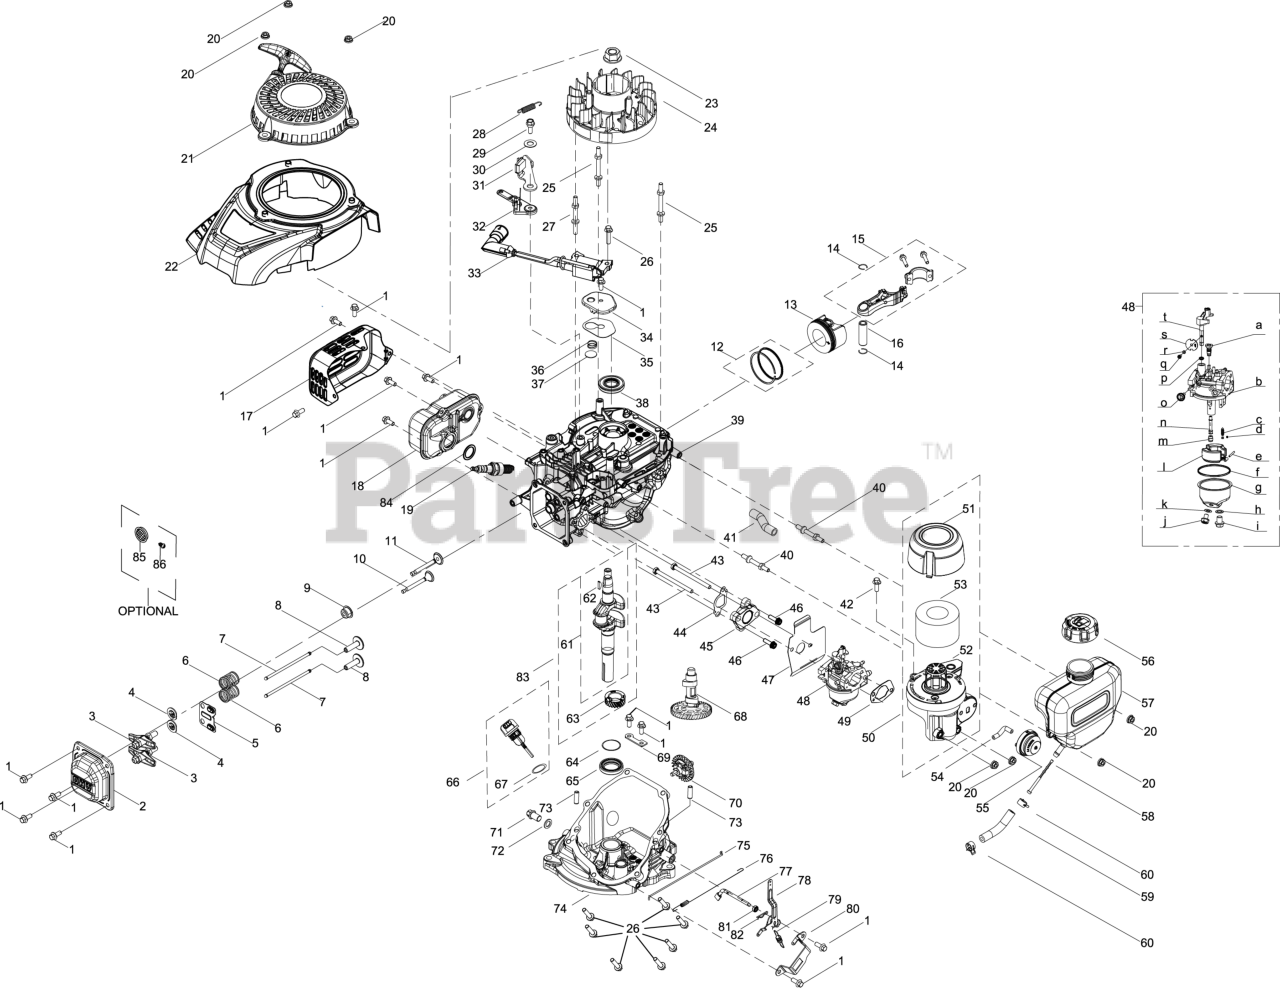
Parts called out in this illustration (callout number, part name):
1	BOLT M6-1 x 14 GR8.8
2	VALVE COVER
4	VALVE RETURN SPRING
5	PUSH ROD GUIDE
6	VALVE SPRING
9	INTAKE VALVE SEAL
10	EXHAUST VALVE
11	INTAKE VALVE
12	PISTON RING SET
14	WRIST PIN CLIP
15	CONNECTING ROD
17	MUFFLER GUARD
19	SPARK PLUG (F6RTC/RN11YC/BPR6ES)
21	STARTER RECOIL ASSEMBLY
22	ENGINE SHROUD
23	FLYWHEEL NUT M14-1.5
24	ENGINE FLYWHEEL
25	STUD M6 x 75
26	BOLT M6-1 x 25 GR8.8
27	STUD M6 x 73
28	ENGINE BRAKE SPRING
29	ENGINE BRAKE PIN M6-1.0 MM
30	FLAT WASHER 10x20x1.0 MM
31	ENGINE BRAKE ARM
32	ENGINE BRAKE LOWER BRACKET
33	IGNITION COIL
34	BREATHER COVER PLATE
35	BREATHER GASKET
36	BREATHER VALVE SPRING
37	BREATHER VALVE
40	FUEL TANK MOUNTING STUD M6X59.5
41	BREATHER HOSE
42	BOLT M6 x 16
43	BOLT M6X80
44	CARBURETOR INSULATION GASKET
45	CARBURETOR INSULATOR
46	BOLT M6X20
47	CARBURETOR GASKET
48	CARBURETOR
49	AIR FILTER BASE GASKET
50	Not Serviceable/ Components Only
51	AIR FILTER COVER
52	AIR FILTER BASE
53	AIR FILTER - FOAM
54	PRIMER HOSE
55	PRIMER ASSEMBLY
56	FUEL CAP ASSEMBLY
58	FUEL FILTER
60	CARBURETOR HOSE CLAMP
61	CRANKSHAFT
62	WOODRUFF KEY
64	THRUST WASHER
65	LOWER CRANKSHAFT SEAL
66	DIPSTICK ASSEMBLY
67	DIPSTICK SEAL
69	GOVERNOR GEAR MOUNTING PLATE
70	GEAR GOVERNOR
71	OIL DRAIN PLUG
72	FLAT WASHER
73	DOWEL PIN 7X20
74	CRANKCASE COVER
75	THROTTLE LINKAGE
76	THROTTLE LINKAGE SPRING
77	GOVERNOR ARM SHAFT
78	GOVERNOR ARM ASSEMBLY
79	GOVERNOR SPRING
80	COMPONENT BRACKET
81	GOVERNOR SEAL
83	CRANKSHAFT
84	MUFFLER GASKET
85	SPARK ARRESTOR
86	SCREW M3.5 x 9.5
